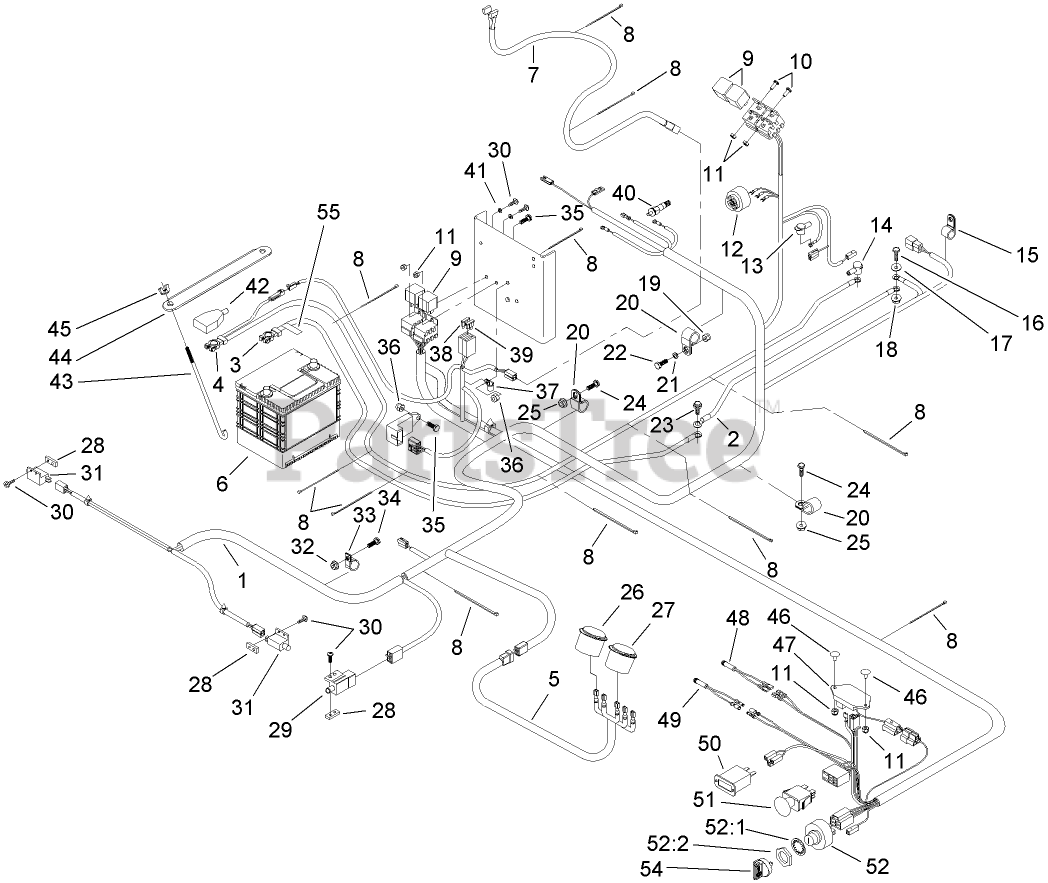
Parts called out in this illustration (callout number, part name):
1	HARNESS-WIRE
2	CABLE-ENGINE NEGATIVE
3	CABLE-BATTERY NEGATIVE
4	CABLE-STARTER
5	HARNESS-GAUGE
6	BATTERY-DRY
7	HARNESS-WIRING, SEAT
8	TIE-PLASTIC
11	NUT-LOCK, NI
12	ALARM-TONE, DUAL
13	CAP-INSULATOR, RED
14	INSULATOR-STARTER
15	CLIP-LOOM
16	SCREW-HH
17	WASHER-FLAT
18	NUT-HHF, WHIZ
19	NUT-LOCK
20	CLIP-LOOM
21	WASHER-FLAT
22	SCREW-HH
23	SCREW-HWHTF
24	SCREW-HH
25	NUT-HF
26	GAUGE-VOLTMETER
27	GAUGE-TEMPERATURE
28	PLATE-TAPPED
29	SWITCH
30	SCREW-PPH
31	SWITCH-OPEN, NORMALLY
32	NUT-HF
33	CLIP-LOOM
34	SCREW-HH
35	SCREW-HH
36	NUT-LOCK, NI
37	CLIP-LOOM
38	FUSE-BLADE TYPE, 20 AMP
39	FUSE-40 AMP
40	SENDER-TEMPERATURE
41	WASHER-FLAT
42	INSULATOR-TERMINAL, BATTERY
43	Bolt-Holddown
44	HOLDDOWN-BATTERY
45	WINGNUT
46	BOLT-CARR
47	MODULE-DELAY, SEAT
48	INDICATOR-LED, RED
49	INDICATOR-LED, AMBER
50	METER-HOUR
51	SWITCH-PTO
52	SWITCH ASM
52:1	NUT-HH
52:2	WASHER-TOOTH, INTERNAL
54	KEY-IGNITION
55	DECAL-INSTRUCTIONS, CHARGING
